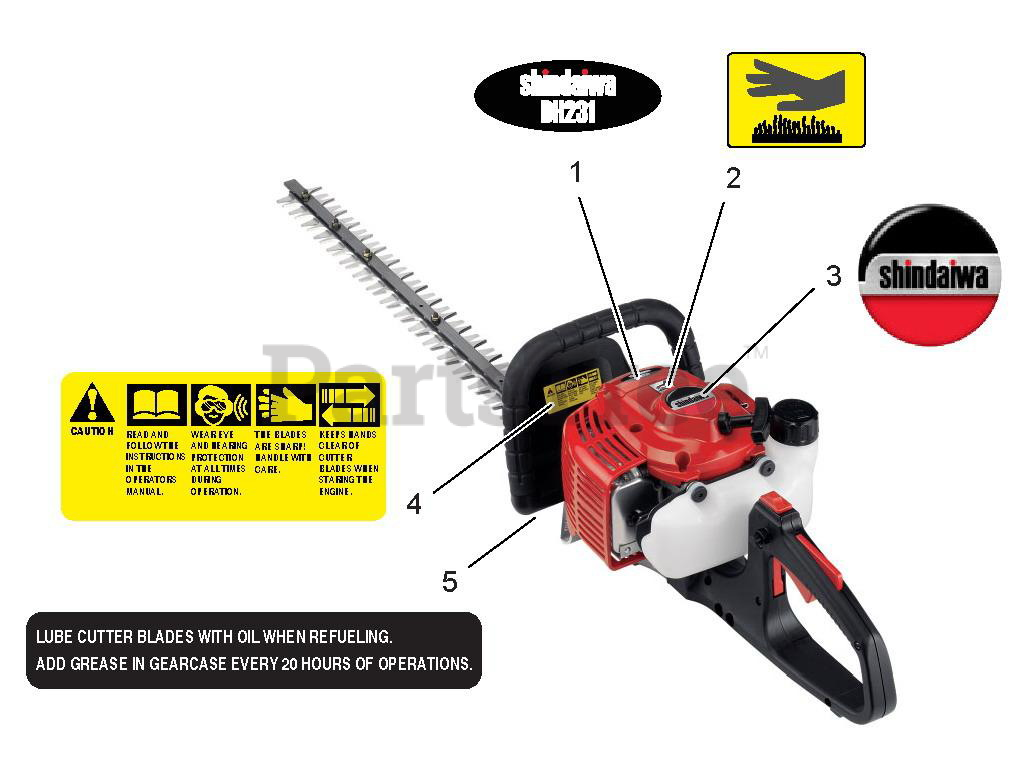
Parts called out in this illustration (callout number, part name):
1	LABEL - MODEL DH231
2	LABEL - HOT SURFACE
3	LABEL - SHINDAIWA
4	LABEL - CAUTION
5	LABEL - BLADE LUBRICATION
